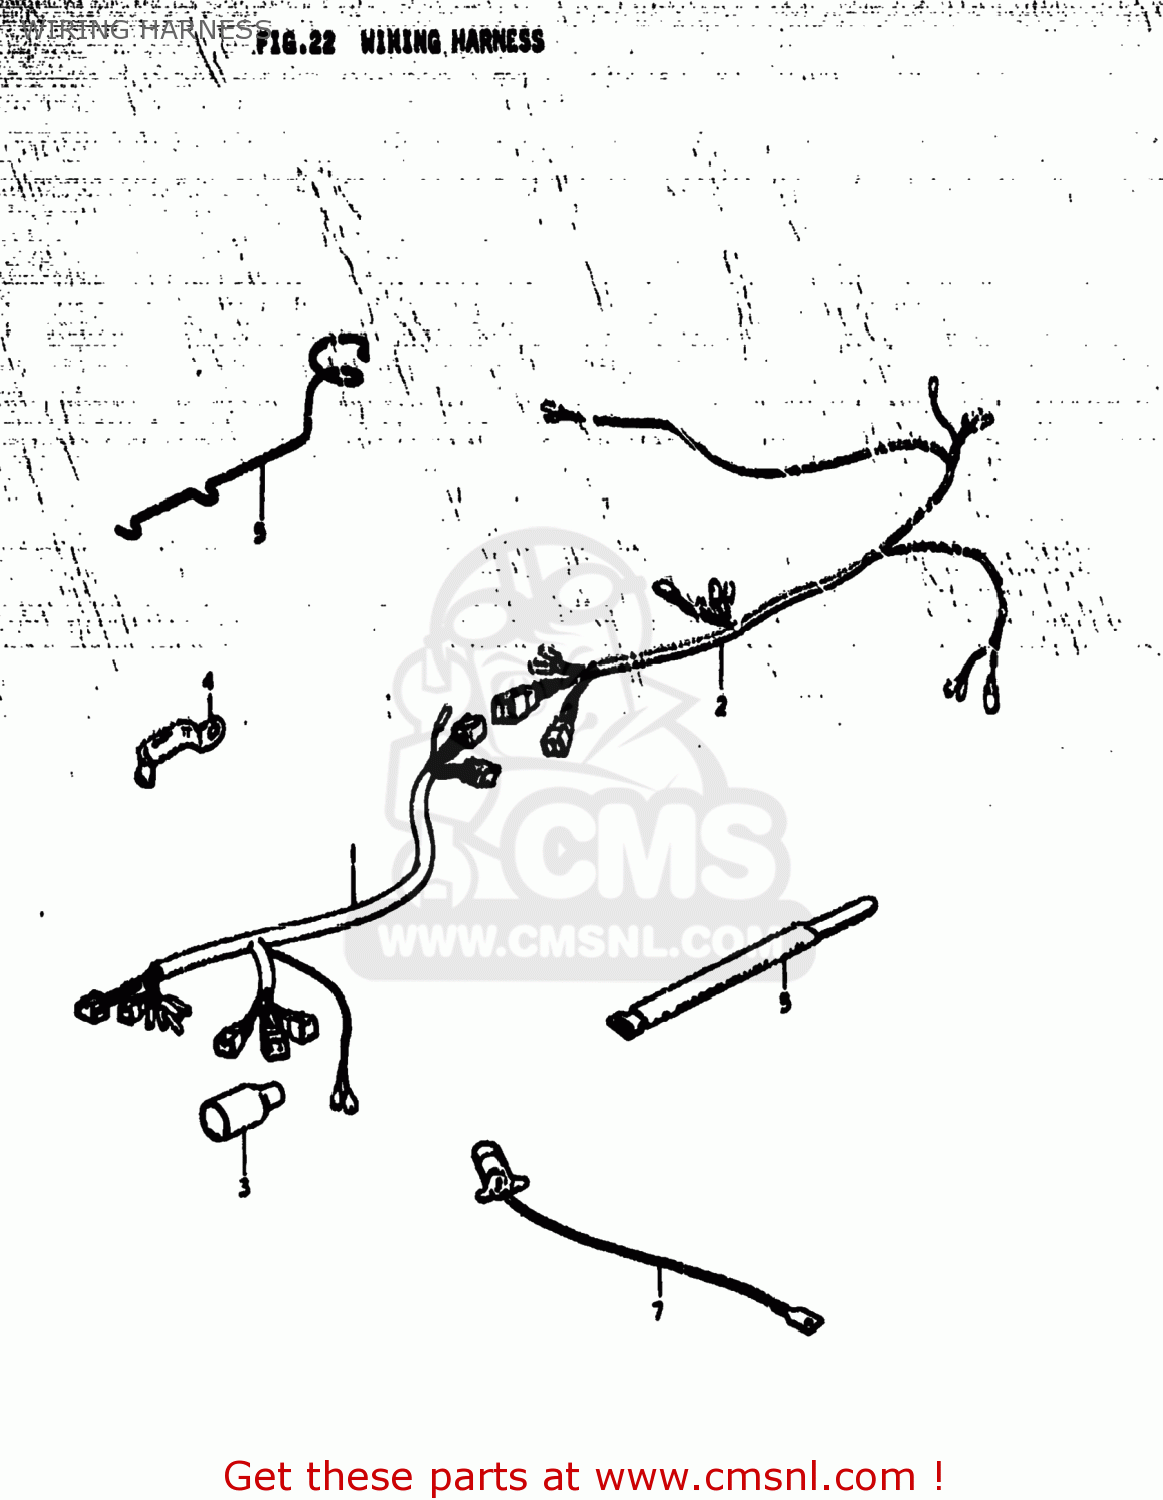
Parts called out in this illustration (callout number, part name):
1	HARNESS,WIRING
2	HARNESS,WIRING NO.2
3	BOOT,WIRING HARNESS
4	CLAMP
5	CLAMP
6	GUIDE,WIRING HARNESS
